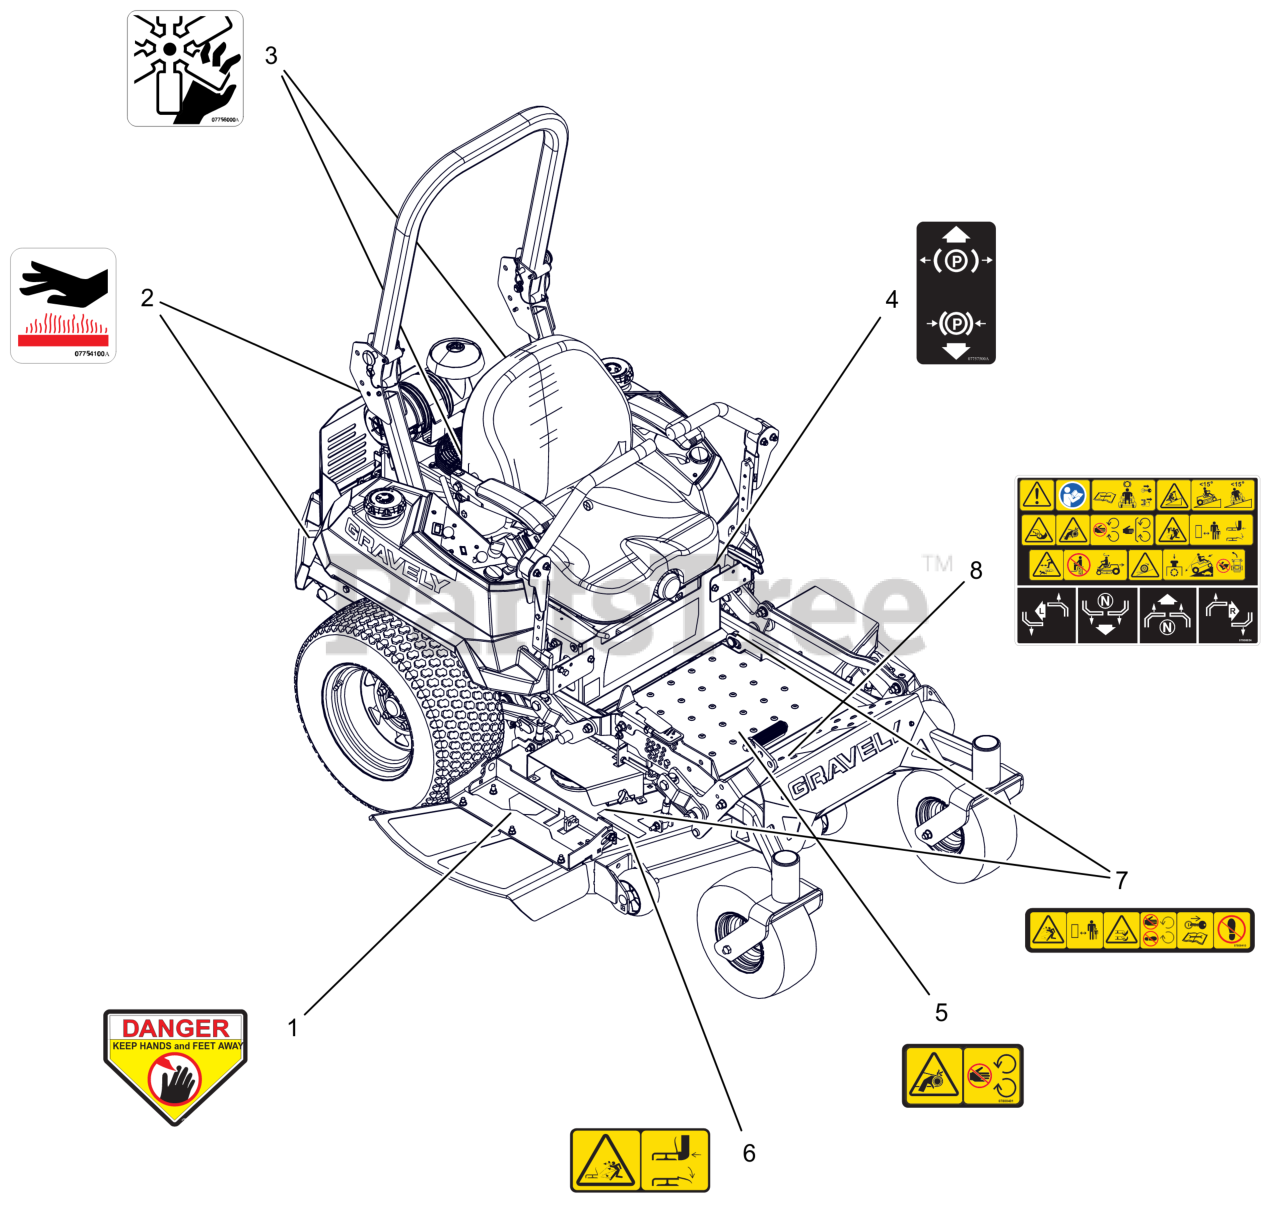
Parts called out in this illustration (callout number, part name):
1	DECAL, DANGER
2	DECAL, HOT SURFACE
3	DECAL, DANGER FAN
4	DECAL, PARKING BRAKE LEVER
5	DECAL, SAFETY - GUARDING
6	DECAL, SAFETY - DECK GUARDING
7	DECAL, DECK SAFETY
8	DECAL, INSTR SAFETY
